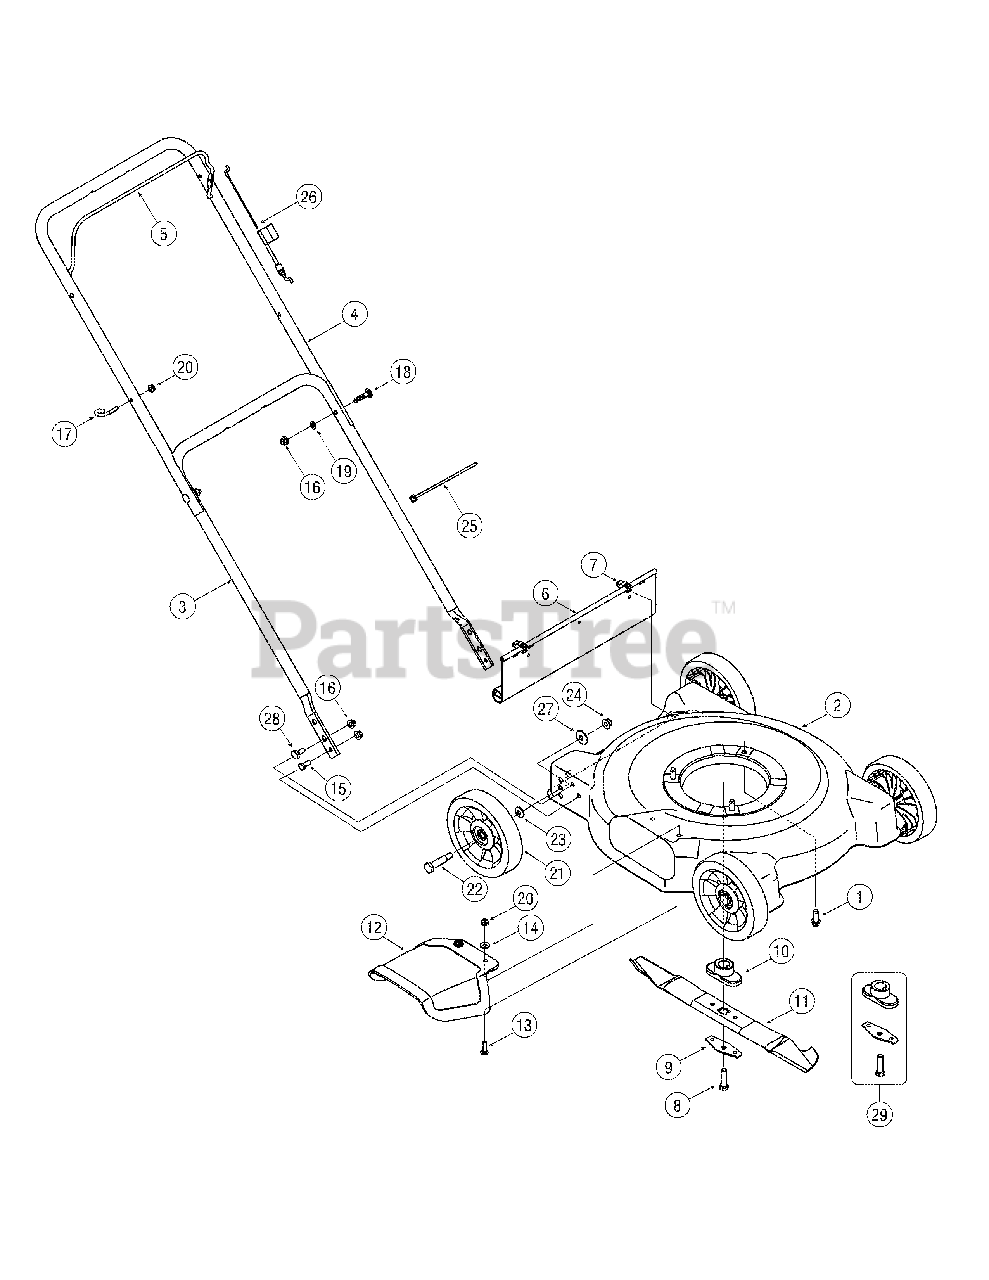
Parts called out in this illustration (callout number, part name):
1	Hex Ind. Washer Screw 3/8-16 x 1.0
6	Rear Flap
7	Hinge Clip
8	Screw 3/8-24 x 1.5" Group 8
9	Blade Bell Support
10	Blade Adapter
11	Cutting Blade
12	Discharge Chute
13	Carriage Screw 1/4-20 x 1.0"
14	Flat Washer
15	Hex Screw 5/16-18 x .75"
16	Flange Lock Nut 5/16-18
17	Eye Bolt
18	Carriage Bolt 5/16-18 x 1.5"
19	Lock Washer
20	Flange Lock Nut 1/4-20
21	Wheel
22	Shoulder Screw .498 x 1.635
23	Bell Washer
24	Flange Lock Nut 3/8-16
25	Cable Tie
26	Control Cable (Model 021)
26	Control Cable (Models 020 & 022)
27	Bell Washer
28	Shoulder Screw, 5/16-18 x.428"
29	Blade Adapter Kit (Incl. Ref. 8-10)
